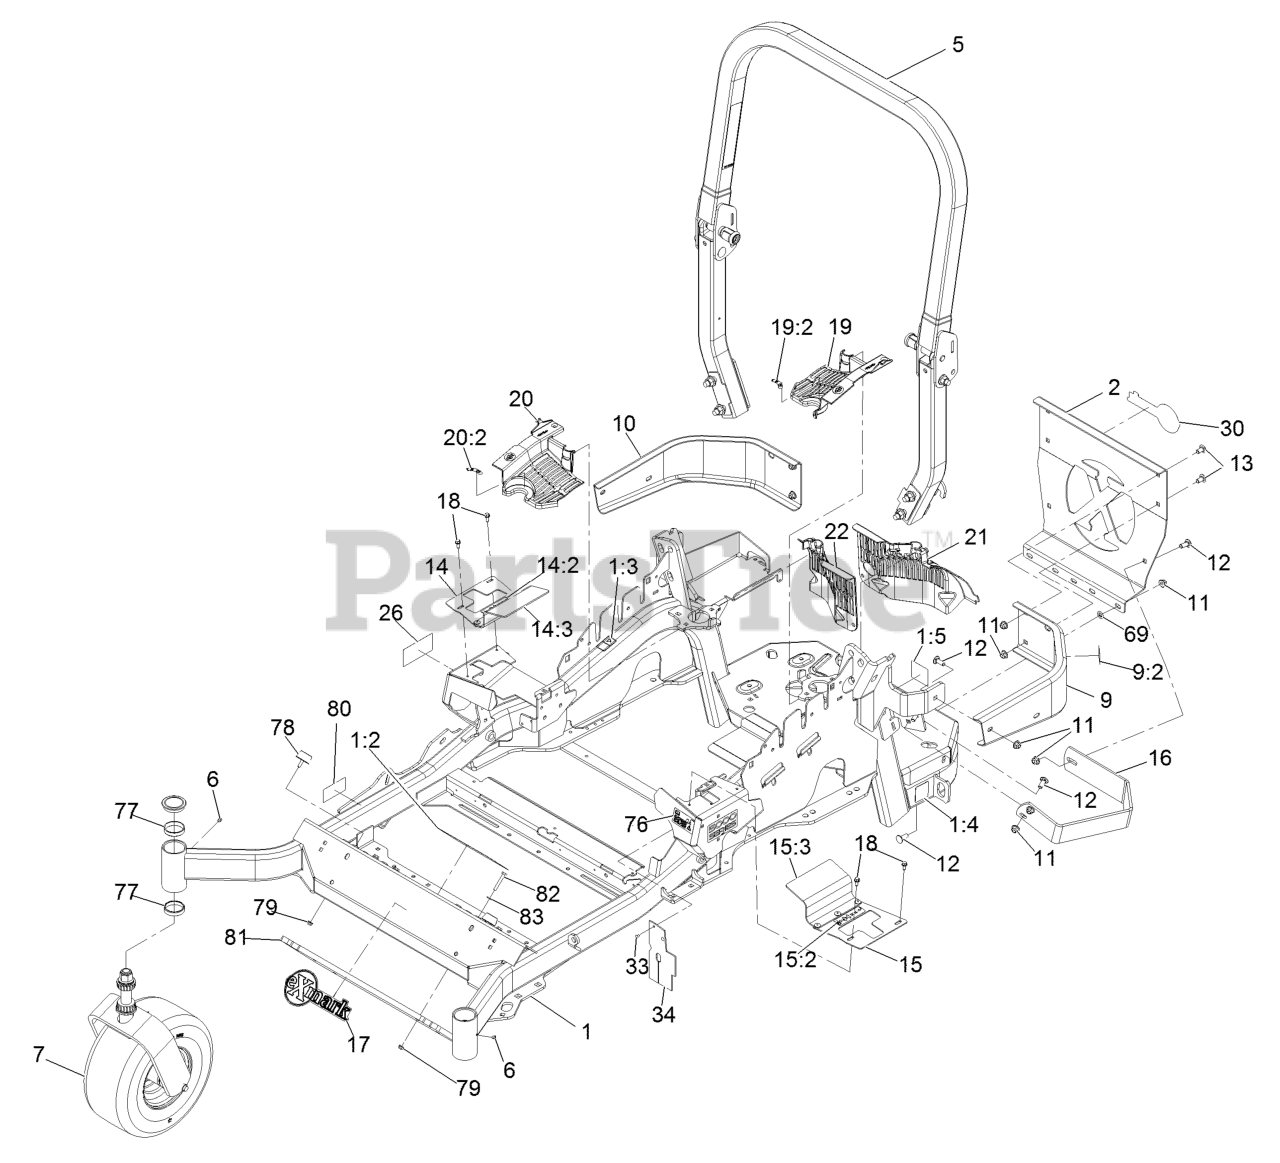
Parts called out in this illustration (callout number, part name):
1	MAINFRAME ASM
1:2	DECAL-DANGER
1:3	DECAL-WARNING
1:4	DECAL-HAZARD, PINCHED FINGER
1:5	DECAL-SPARK ARRESTER
2	PLATE,REAR GUARD
5	ASM,ROPS SERVICE EXMARK
7	Caster Wheel ASM
9	LH BUMPER ASM
9:2	DECAL-WARNING
10	BUMPER-RH
11	NUT-HF, NI
12	SCREW-CARR
13	SCREW-CARR
14	RH MOTION CONTROL COVER A
14:2	DECAL-CONTROL, MOTION
14:3	FLAP-RUBBER
15	LH MOTION CONTROL COVER A
15:2	DECAL-CONTROL, MOTION
15:3	FLAP-RUBBER
16	GUARD-MUFFLER
17	DECAL-EXMARK LOGO
18	SCREW-HWH
19	LH HYDRO GUARD ASM
19:2	DECAL-OIL, HYDRO
20	RH HYDRO GUARD ASM
20:2	DECAL-OIL, HYDRO
21	GUARD-HYDRO REAR, LH TRIM
22	GUARD-HYDRO, REAR (RH)
26	DECAL-X-SERIES
30	DECAL-EXMARK LOGO
33	RIVET-POP
34	DEFLECTOR-AIR FLOW
69	NUT-PUSH
76	DECAL-FUEL FILL, CE
77	CUP-BEARING
80	Decal-Patent Ttco.Com
81	WEIGHT-TOE BOARD
82	SCREW-HH
83	WASHER-FLAT
